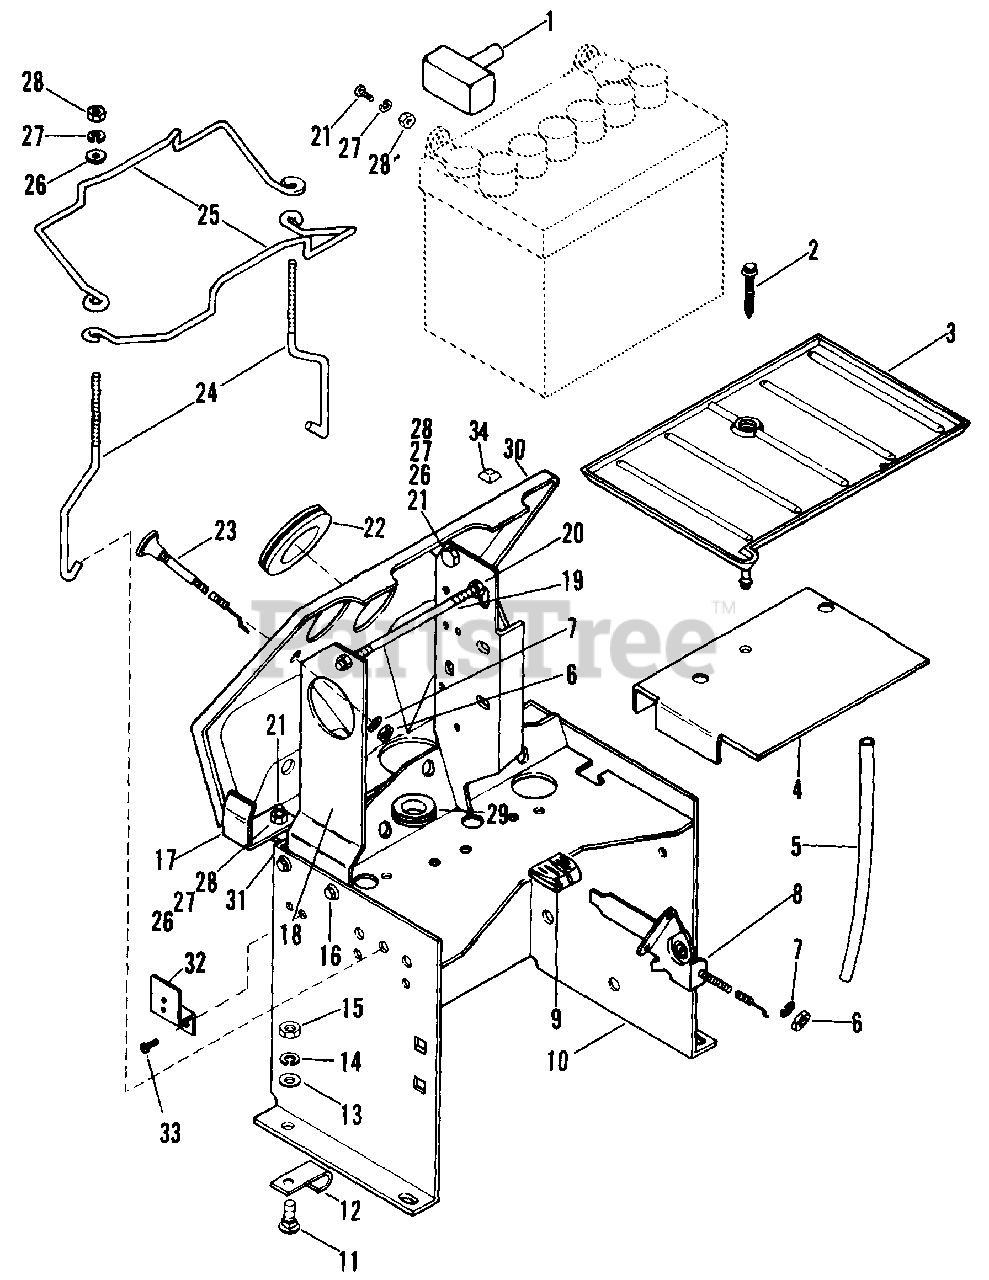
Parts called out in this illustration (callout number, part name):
1	Insulator
2	Screw, Tapping #12-14 x 1.50 OVHPL
3	Battery Tray
4	Battery Stand
5	Hose, Drain
6	Nut, #10-24 Hex
7	Washer, Lock No. 10 SP
8	Throttle Control
9	Knob
10	Dash Support
11	Bolt, Carriage 5/16-18 x .75
12	Clip
13	Washer, Flat .375 x .734 x .065
14	Washer, Lock 5/16 SP
15	Nut, Hex 5/16-18
16	Taptite, 1/4-20 x .50
17	Clip
18	Hourmeter Mounting Plate
19	Brace Rod
20	Nut, Lock 1/4-20
21	Bolt, Hex 1/4-20 x .875
22	Grommet
23	Choke Control
24	Tie Down
25	Hold Down
26	Washer, Flat .281 x .625 x .065
27	Washer, Lock 1/4 Reg.
28	Nut, Hex 1/4-20
29	Grommet
30	Dash
31	Screw, Tapping #10-16 x .50 HWHPL
32	Bracket, Hood Latch Mtg.
33	Screw, Tapping #8-15 x .375 R.H.
34	Stop
NS	Instruction Decal
NS	Rear Implement Decal
NS	Decal, Danger
